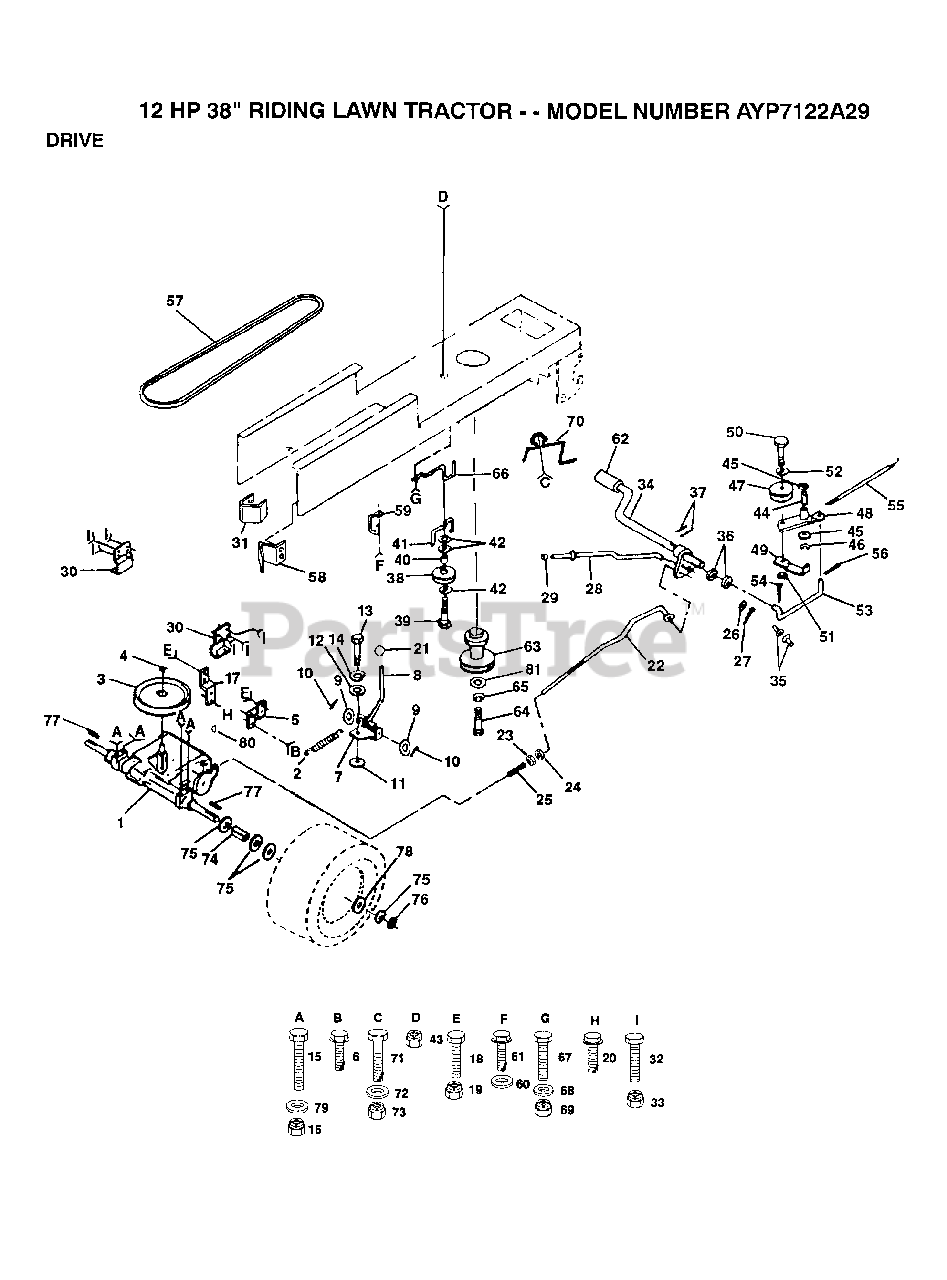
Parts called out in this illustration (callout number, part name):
3	PULLEY TRANS
5	STRAP TORQUE
6	SCREW
7	PLATE SHIFT LT
8	SHIFTER ROD
9	WASHER
11	WASH-SHFT PLT LT
12	WASHER LT
14	LOCKWASHER
15	BOLT
17	STRAP TORQUE
20	SCREW
21	KNOB T (1/2-HOLE)
23	NUT
25	SPRING ROD LT
26	WASHER
28	PARKING BRAKE ROD
29	PLUNGER CAP T
30	BRACKET LT
31	"KEEPER,BELT LH T"
35	NYLON BEARING
36	WASHER LT
38	PULLEY.IDLER.FLAT
39	BOLT
40	SPACER T
41	BELT KEEPER LT
42	WASHER
44	"LY, BEARING"
45	WASHER LT
46	KLIP RING
48	ARM IDLER
49	RETAIN BELT
52	WASHER
53	"LINK, CLUTCH T"
55	"SPRING, RETURN LT"
57	BELT-V.90.0.GD.DR
58	"KEEPER,BELT RH T"
60	WASHER
61	SCREW
62	PEDAL COVER T
65	LOCKWASHER
66	KEEPER.BELT.ENG.L
67	BOLT
68	WASHER
70	GUIDE BLT DR MWR
71	BOLT
72	WASHER
75	WASHER
76	E-RING LT
77	SQUARE KEY
78	WASHER
79	WASHER
81	WASHER
